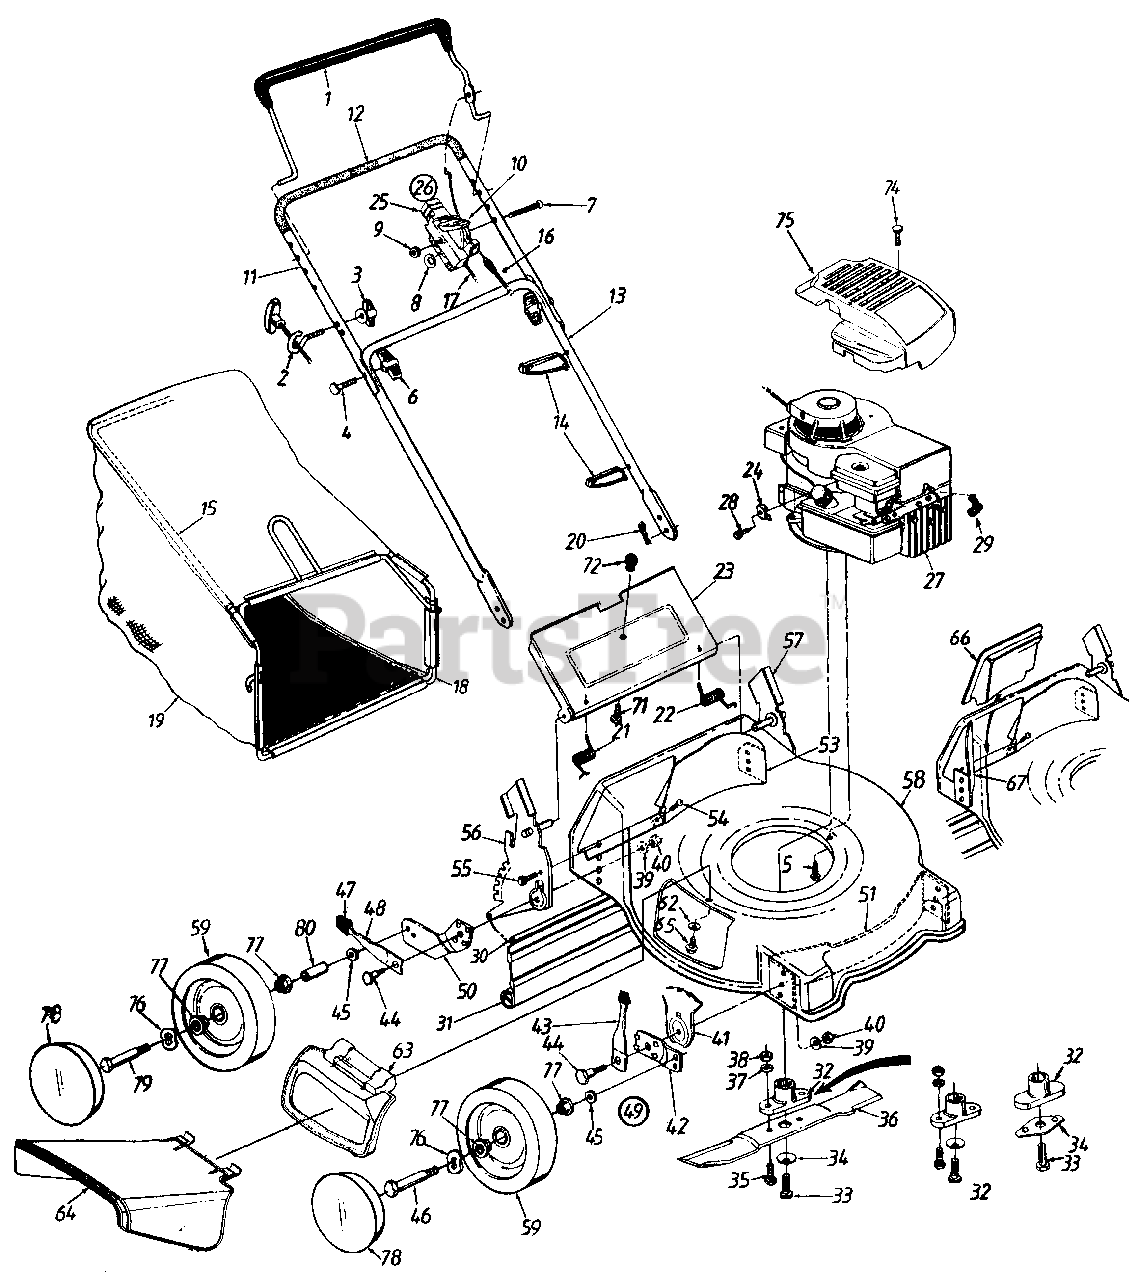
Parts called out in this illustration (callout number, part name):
1	Control Handle Ass'y.
3	Handle Knob 1/4-20 Thd.
4	Curved Hd. Bolt 5/16-18 x 2" Lg.
6	Hand Knob
7	Oval C-Sunk Mach. Scr.
8	Spr. Wash. .66" I.D.
9	Hex L-Nut 1/4-20 Thd.
10	Throttle Lever
14	Cable Tie
16	Control Cable - 36"
17	Throttle Control Wire - 55"
20	Int. Cotter Pin 5/16" Dia.
21	Door Spring - R.H.
22	Door Spring - L.H.
25	Throttle Body
26	Throttle Box Comp.
27	Engine
28	Hex Wash. Hd. Scr. #10-32 x .62" Lg.
29	Spark Plug Boot
30	Wire Rod
31	Rear Flap
32	Blade Adapter Kit
33	Hex Bolt 3/8-24 x 1.5" Lg.
34	Blade Bell Support
35	Hex Bolt 3/8-24 x 1" Lg.
36	21" Mulching Blade
37	L-Wash. 3/8" I.D.
38	Hex Nut 3/8-24 Thd.
39	Bell-Wash. .39" I.D. x 1.38"
40	Hex Nut 3/8-16 Thd.
41	Height Adj. Plate
43	Spring Lever Ass'y. w/Knob
44	Shld. Bolt .5" Dia. x .357"
45	Bell-Wash. .38" I.D. x .88" O.D.
46	Front Axle Bolt
47	Spring Lever Knob
49	Weight Adj. Ass'y. Comp. - R.H.
54	Torx Mach. AB-Tap Scr. 1/4 x .62" Lg.
55	Hex L-Wash. Hd. AB-Tap Scr. 1/4 x .62" Lg.
63	Hinged Mulching Plug
64	Chute Deflector
71	Truss Scr. #10-24 x .38" Lg.
74	Hi-Lo Scr. #10 x 1.25" Lg.
75	XTL Grey Shroud
76	Wave Washer
77	Ball Bearings
78	Hub Cap
79	Rear Axle Bolt
80	Spacer
